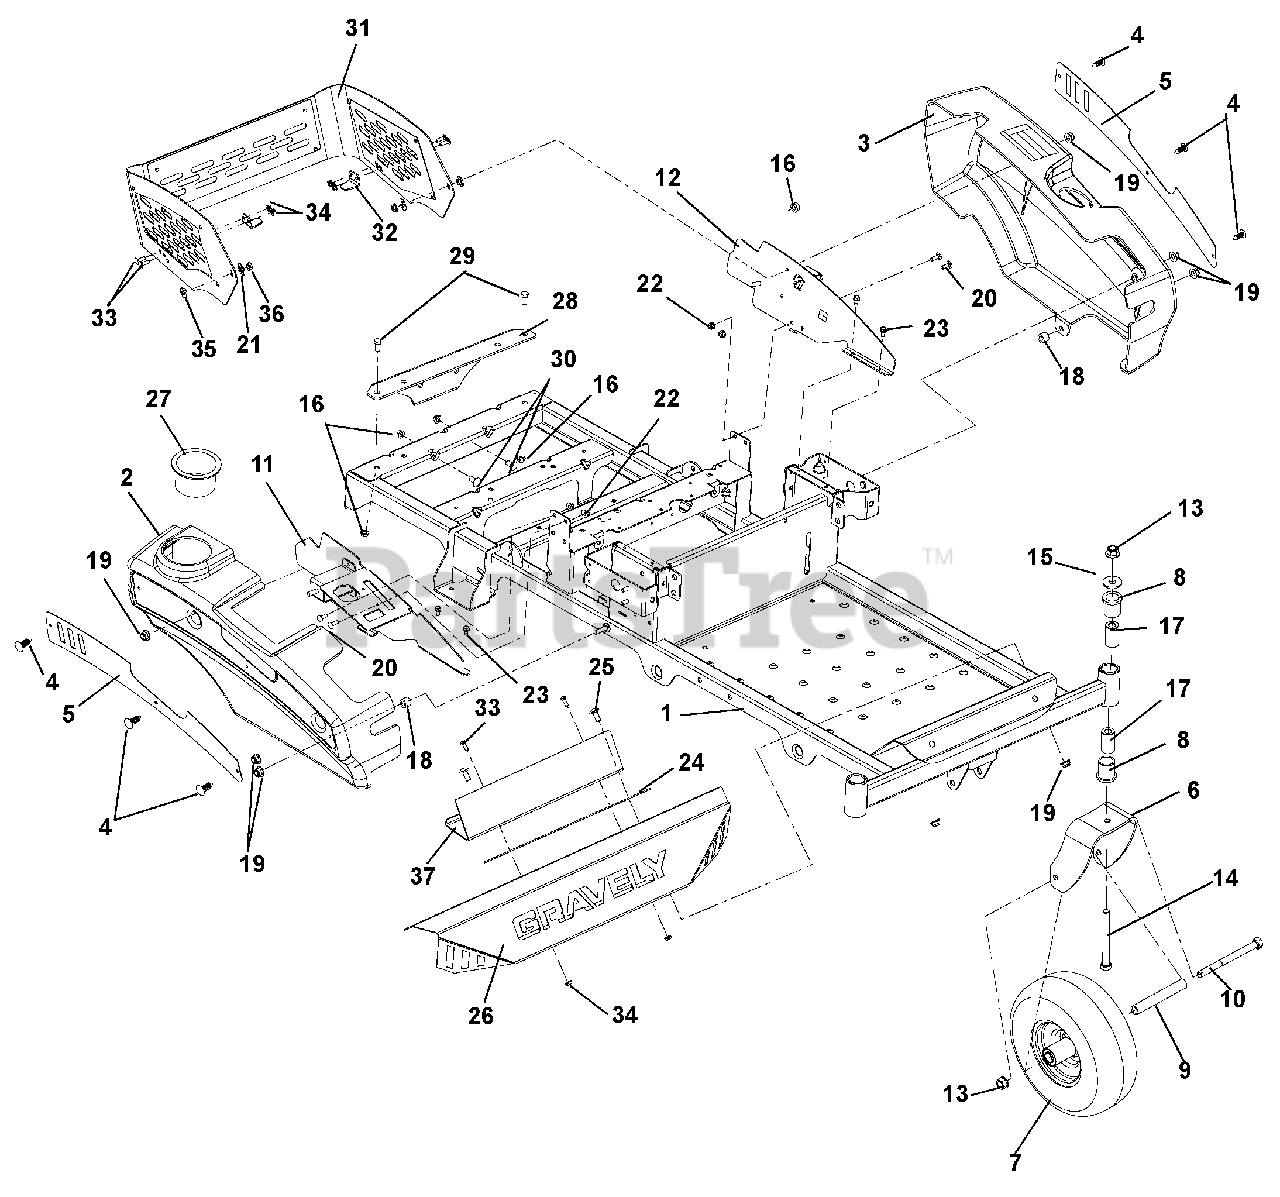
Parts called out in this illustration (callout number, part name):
1	Weldment, Frame
2	Fender, Right Hand
3	Fender, Left Hand
4	Rivet, Nylon
5	Plate, Fender
6	Fork, Caster
7	Wheel/Tire Assembly, 11.0 x 4.0 x 5.0
8	Bushing, Flange 1.00 x 1.25 x 1.50 x 1.50
9	Spacer, Wheel
10	Bolt, Hex .50-13 x 6.50
11	Weldment, Fender Mount Right Hand
12	Weldment, Fender Mount Left Hand
13	Nut, Locking, Top, Flange .50-13
14	Bolt, Hex .50-13 x 5.00
15	Washer, Flat Steel .511 x 1.441 x .125
16	Nut, Locking, Top, Flange .38-16 (915328)
17	Spacer, Caster
18	Bushing, Sleeve .391 x .688 x .52
19	Nut, .31-18 Nyloc Flange
20	Bolt, Round Head Square Neck .25-20 x .75
21	Washer, Flat, Nylon .52 x 1.00 x .08
22	Nut, .25-20 Nyloc Flange
23	Screw, Tapping .25-20 x .50 Hex Washer Head Thread
24	Grip, Adhesive (1" x 16" BLK)
25	Bolt, Round Head Square Neck .31-18 x .75
26	Foot Rest
27	Cupholder
28	Plate, BBZ Hitch Kit Plate (915328)
29	Bolt, Hex .38-16 x .75 (915328)
30	Bolt, Round Head Square Neck .31-16 x .75 (915328)
31	Assembly, Engine Wrap
32	Bracket, Engine Wrap Foot
33	Bolt, Round Head Square Neck .25-20 x .50
34	Nut, Center Lock Flange .25-20
35	Bushing, Flange .325 x .499 x .3 x .875
36	Nut, Center Lock Flange .31-18
37	Plate, Back Foot Rest
